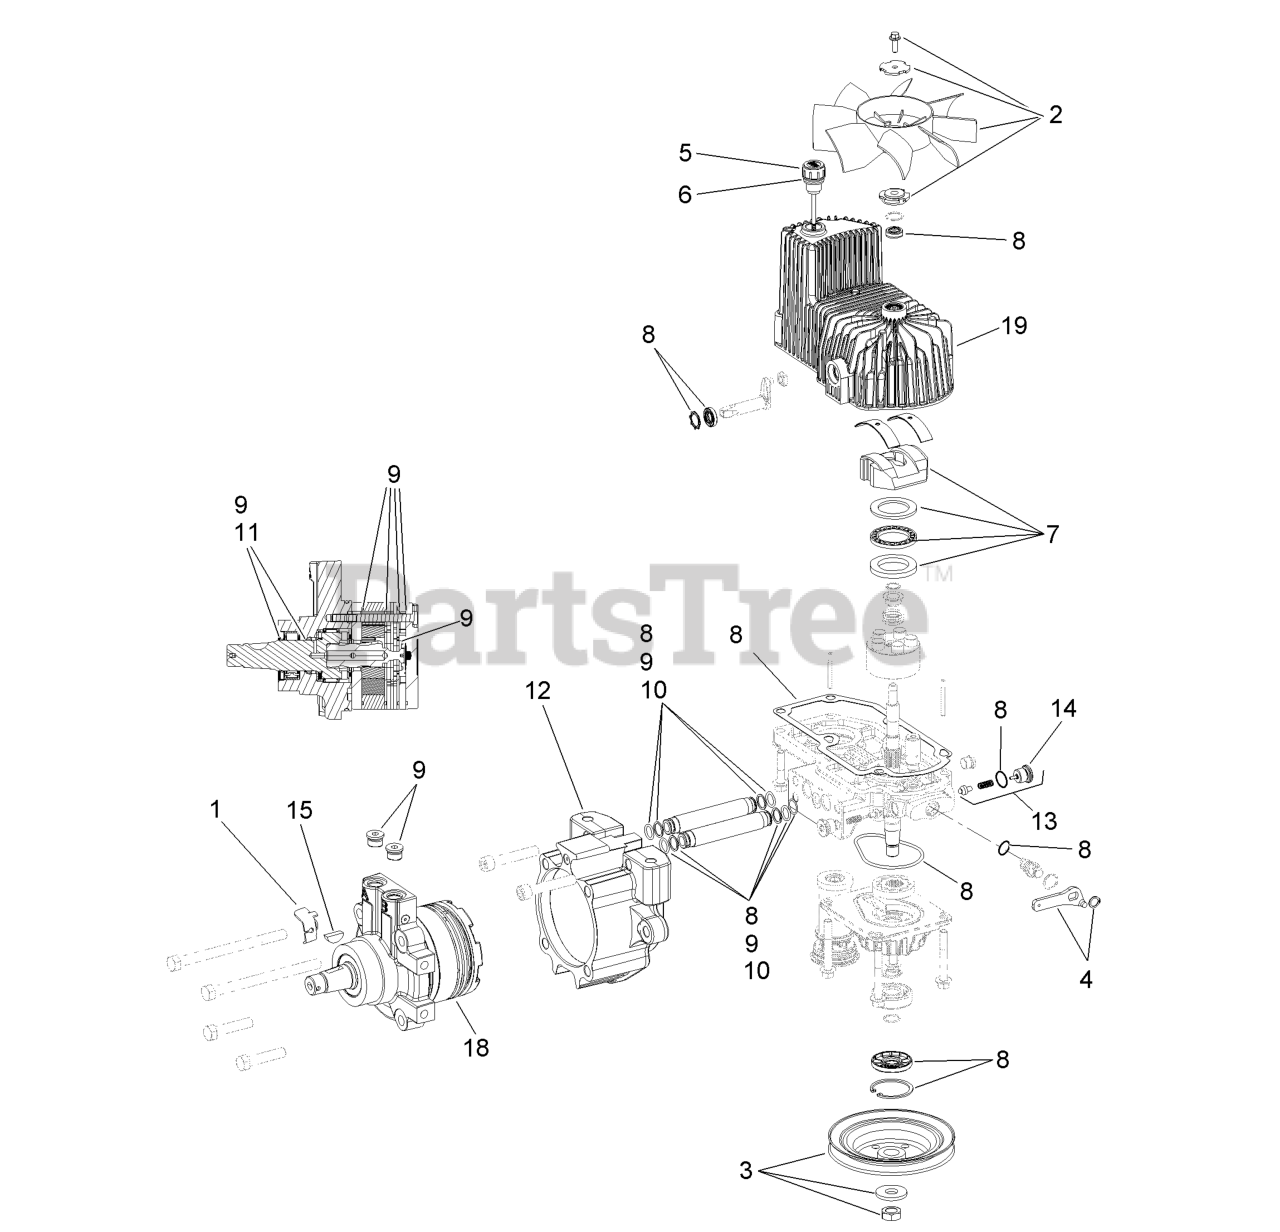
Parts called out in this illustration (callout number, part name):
1	BRACKET-ANCHOR, CABLE
2	FAN KIT
3	PULLEY KIT
4	HANDLE-BYPASS VALVE, HYDRO
5	DIPSTICK-HYDRO W/GASKET
6	GASKET-DIPSTICK, HYDRO
7	SWASH BLOCK KIT
8	PUMP SEAL KIT
9	MOTOR SEAL KIT
10	TUBE SEAL KIT
11	OUTPUT SHAFT SEAL KIT
13	CHECK VALVE ASM
14	PLUG-CHECK (W/O-RING)
15	KEY-WOODRUFF
19	HOUSING-HYDRO, LH
